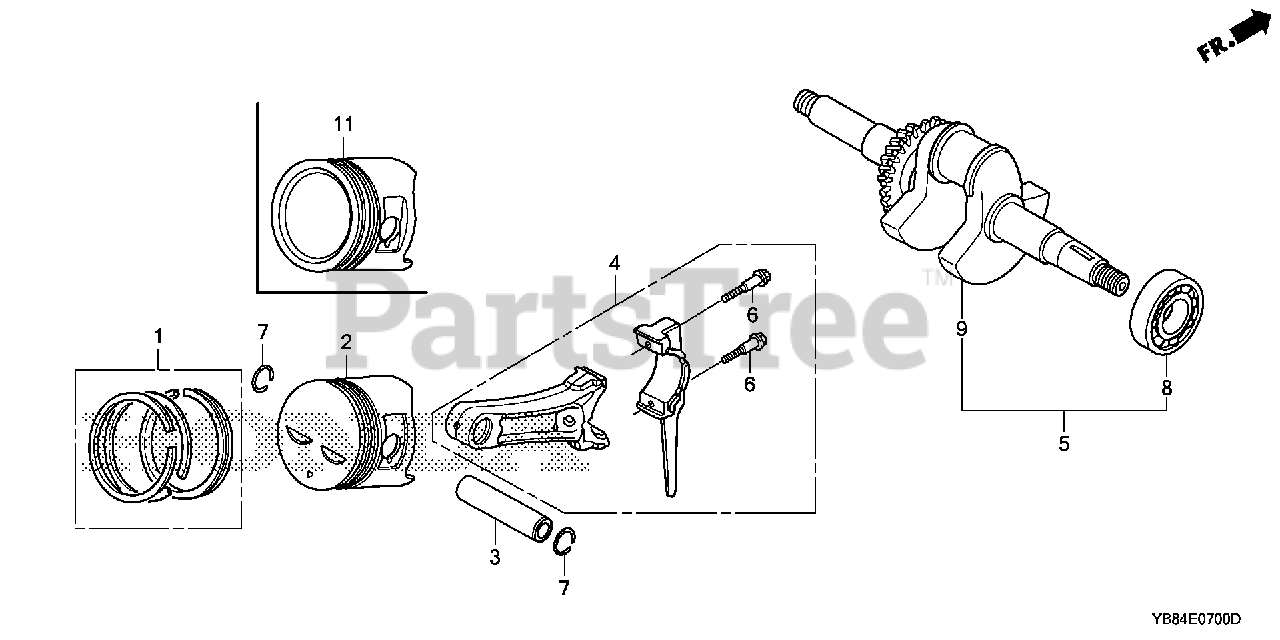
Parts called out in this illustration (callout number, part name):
1	RING SET, PISTON (STD) (NIPPON)
1	RING SET, PISTON (STD) (TEIKOKU)
1	RING SET, PISTON (0.25) (NIPPON)
1	RING SET, PISTON (0.25) (TEIKOKU)
1	RING SET, PISTON (0.50) (NIPPON)
1	RING SET, PISTON (0.50) (TEIKOKU)
1	RING SET, PISTON (0.75) (NIPPON) (NOT AVAILABLE)
1	RING SET, PISTON (0.75) (TEIKOKU)
1	RING SET, PISTON (0.75) (NIPPON)
2	PISTON (STD)
2	PISTON (0.25)
2	PISTON (0.50)
2	PISTON (0.75)
3	PIN, PISTON
4	ROD ASSY., CONNECTING (0.25 LOWER SIZE)
4	ROD ASSY., CONNECTING (STD)
5	CRANKSHAFT
6	BOLT, CONNECTING ROD
7	CLIP, PISTON PIN (18MM)
8	BEARING, RADIAL BALL (6206)
